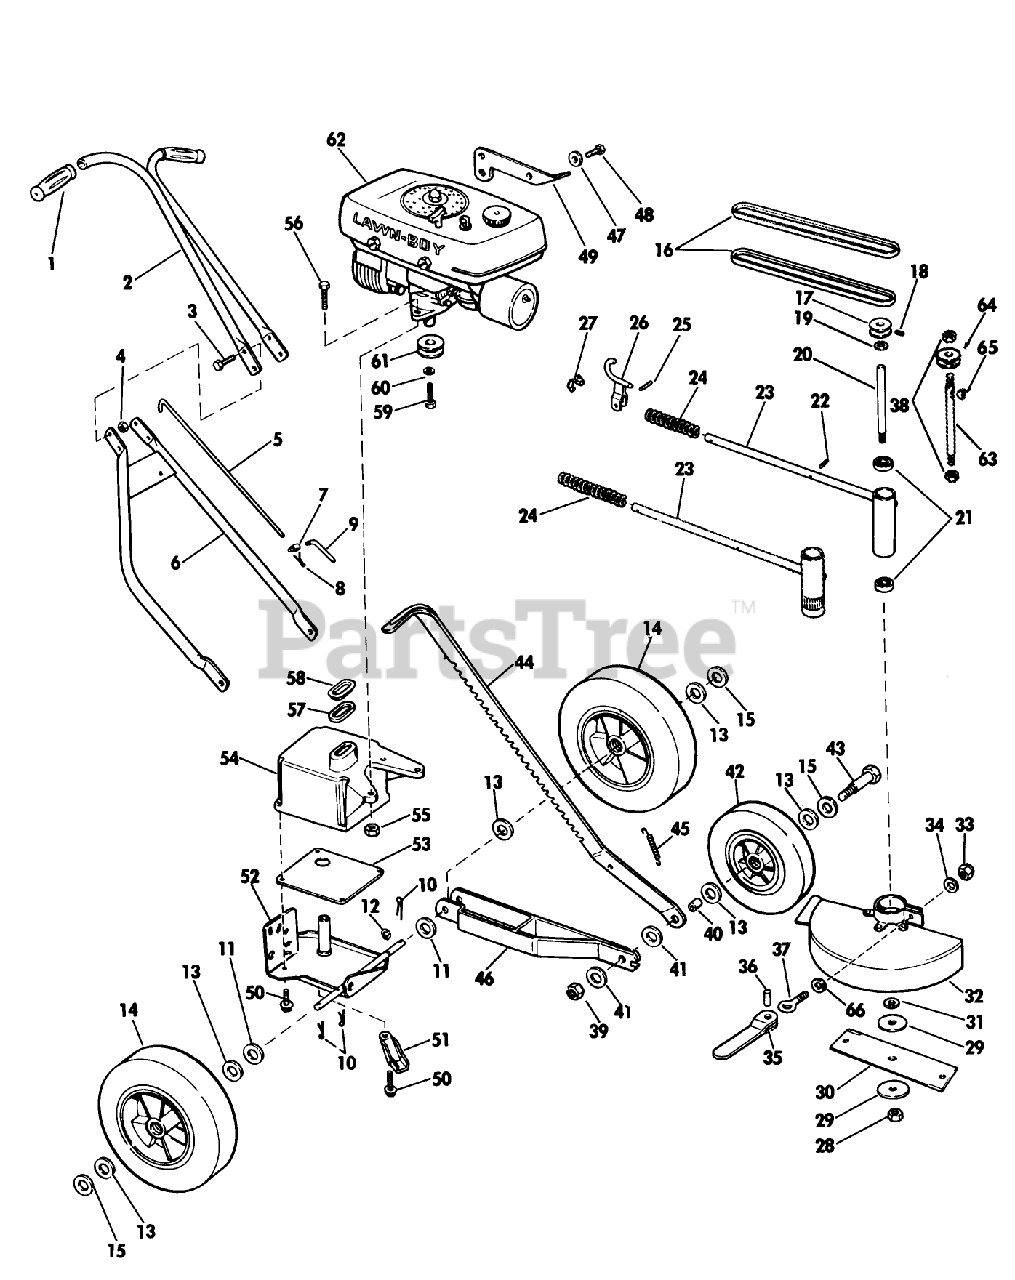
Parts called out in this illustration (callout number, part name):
1	HANDLE GRIP
23	Spindle Housing Pivot Assy.
30	Blade-9"
36	Roll Pin
39	LOCKNUT
57	GASKET S
60	WASHER, LOCK
66	WASHER WROUGHT
